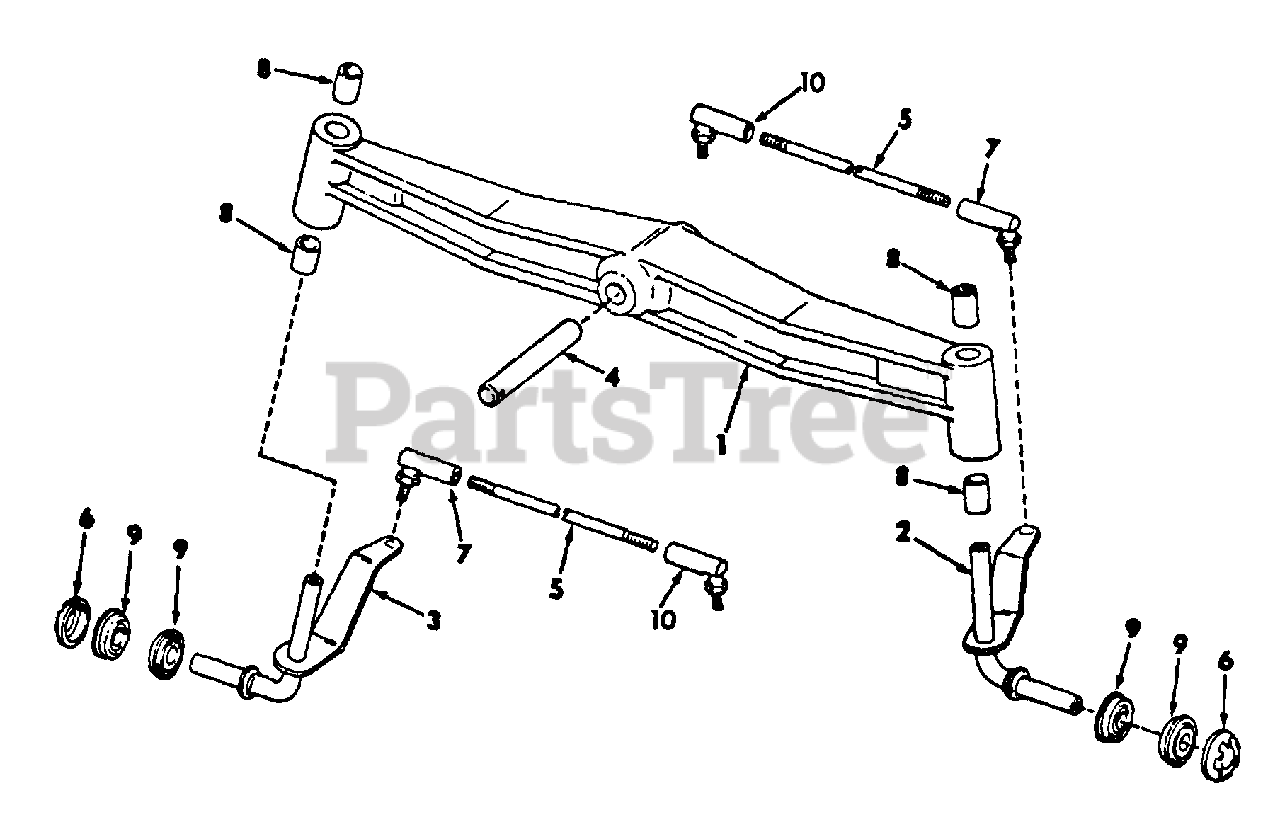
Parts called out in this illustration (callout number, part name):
1	AXLE ASSY, FRONT
2	KNUCKLE ASSY, STEERING LH
3	KNUCKLE ASSY. STEERING RH
4	PIN, FRONT AXLE PIVOT
7	JOINT TIE ROD BALL - OUTER
8	BUSHING, FRONT AXLE
9	BEARING ASSY, WHEEL BALL
10	JOINT TIE ROD BALL - INNER
